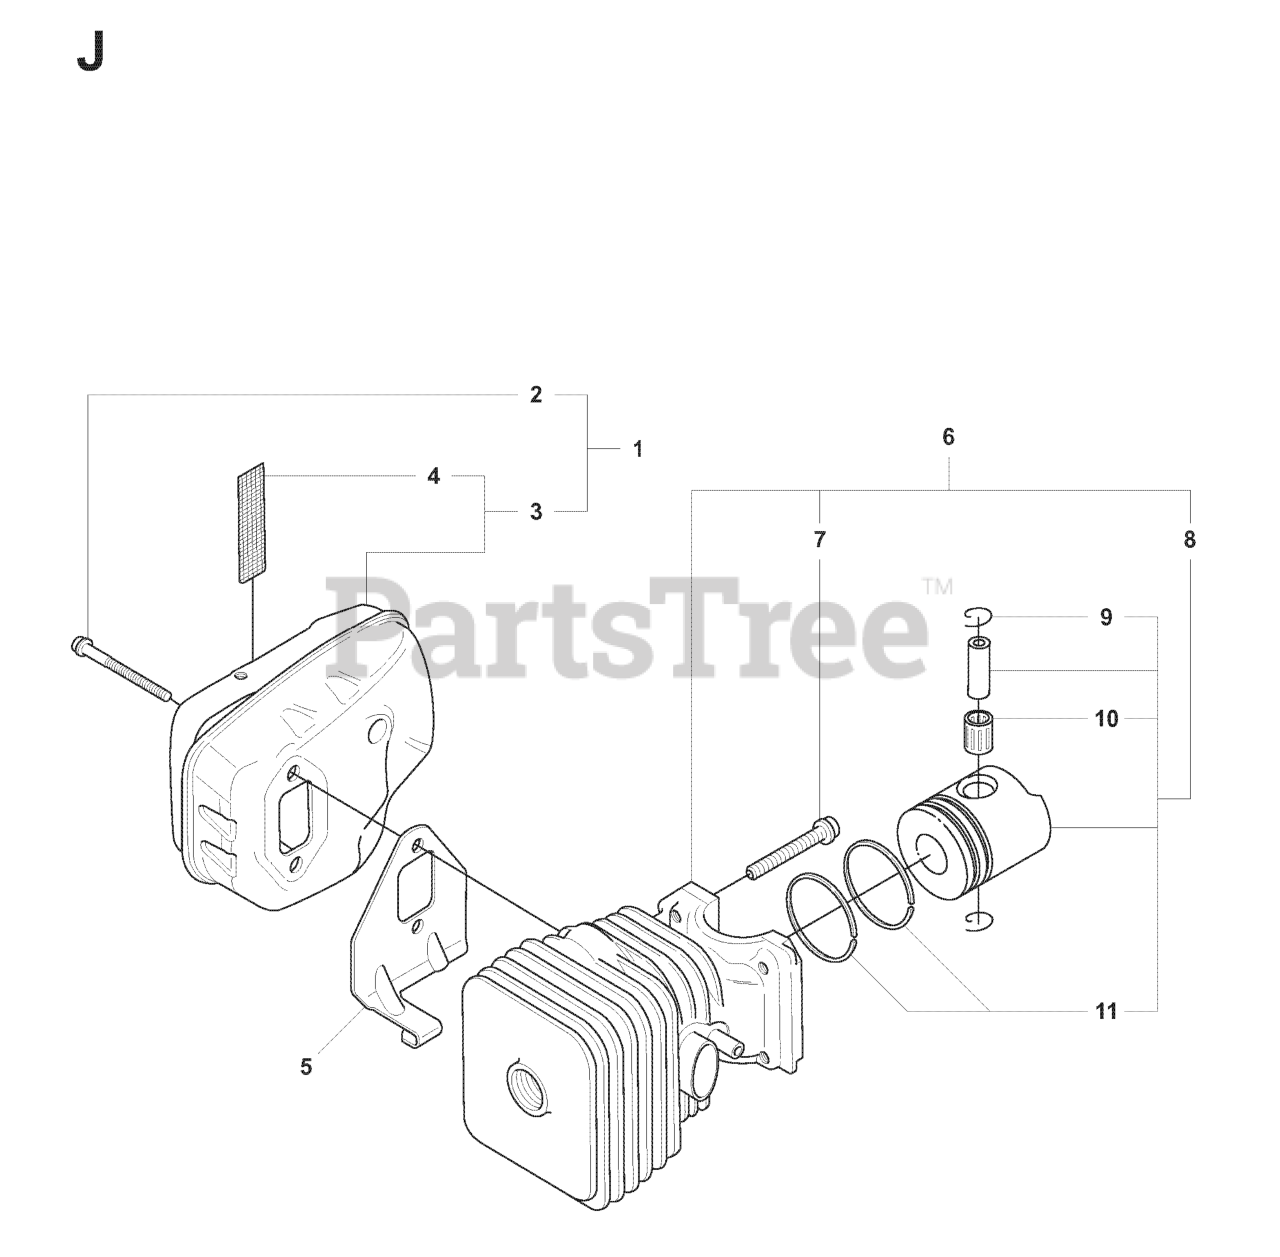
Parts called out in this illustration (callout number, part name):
4	SPARK ARRESTOR SCREEN
6	CYLINDER
7	SCREW MC6S 5X35
8	PISTON
11	PISTON RING
